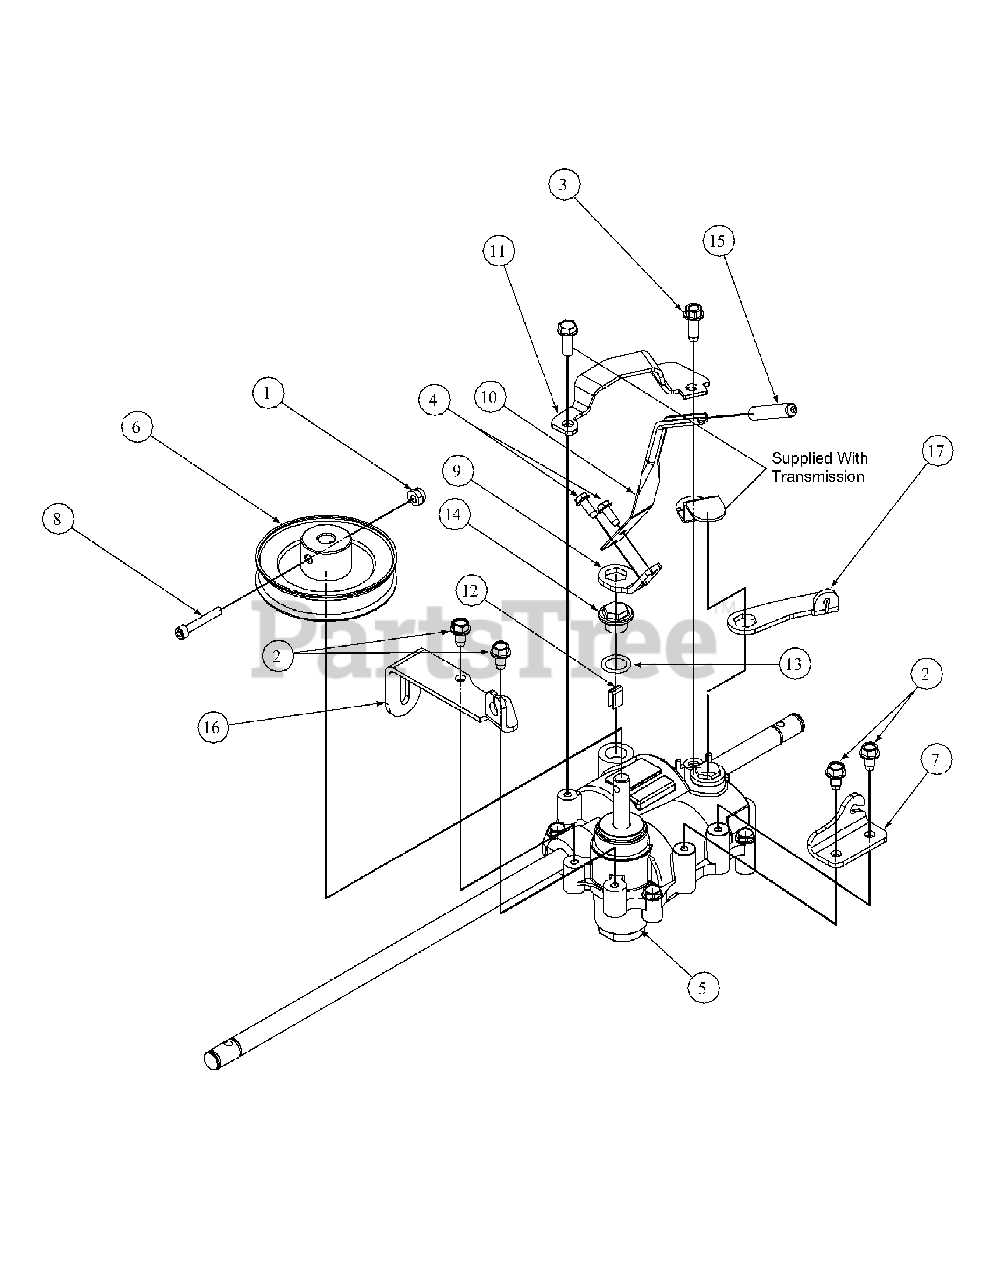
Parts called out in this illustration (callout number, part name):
1	Nylon Lock Nut, #10-24
2	Hex Index Washer Screw, 1/4-20 x .5
3	Hex Index Washer Screw, 1/4-20 x .75
4	Hex Index Washer Screw, #10-24 x .5
5	3-Speed Transmission
6	Transmission Pulley, 3/8V x 3.50 OD
7	Transmission Spring Bracket
8	Socket Screw, 10-24 x 1.25
9	Shift Bracket
10	Shift Lever
11	Retainer Shift Bracket
12	21" Self Propelled Shim
13	3-Speed O-ring Seal
14	3-Speed Clutch Cap
15	21" Shifter Sleeve
16	Transmission Clutch Bracket
17	3-Speed Clutch Plate
